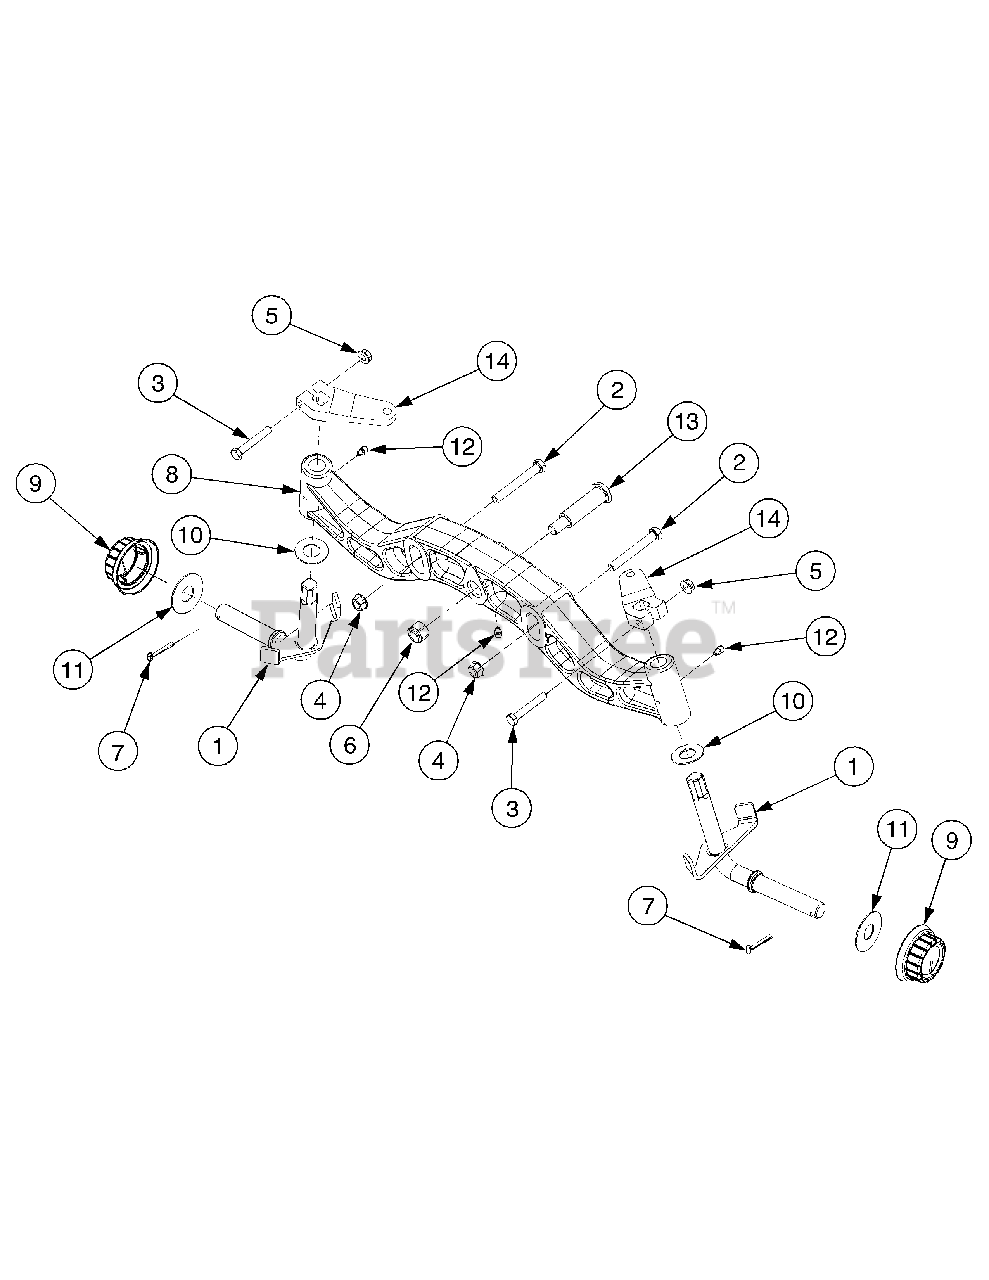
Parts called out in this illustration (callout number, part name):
1	Axle Assembly
2	Screw, Hex Cap, 3/8-16 x 2.75 GR8
3	Screw, Hex Cap, 5/16-18 x 2 GR5
4	Nut, Hex Flanged Lock, 3/8-16
5	Nut, Hex Flange Top Lock, 5/16-18
6	Nut, Hex Top Nylon Lock, 1/2-13
7	Pin, Cotter, 5/32 x 1.25
8	Axle, Front Pivot
9	Hubcap
10	Washer, Flat, .760 x 1.49 x .06 Thk.
11	Washer, Flat, .755 x 1.92 x .06
12	Fitting, Lube, 3/16 Drive Type
13	Bolt, Pivot Shoulder, 3/4 Dia x 2.23
14	Arm, Steering
